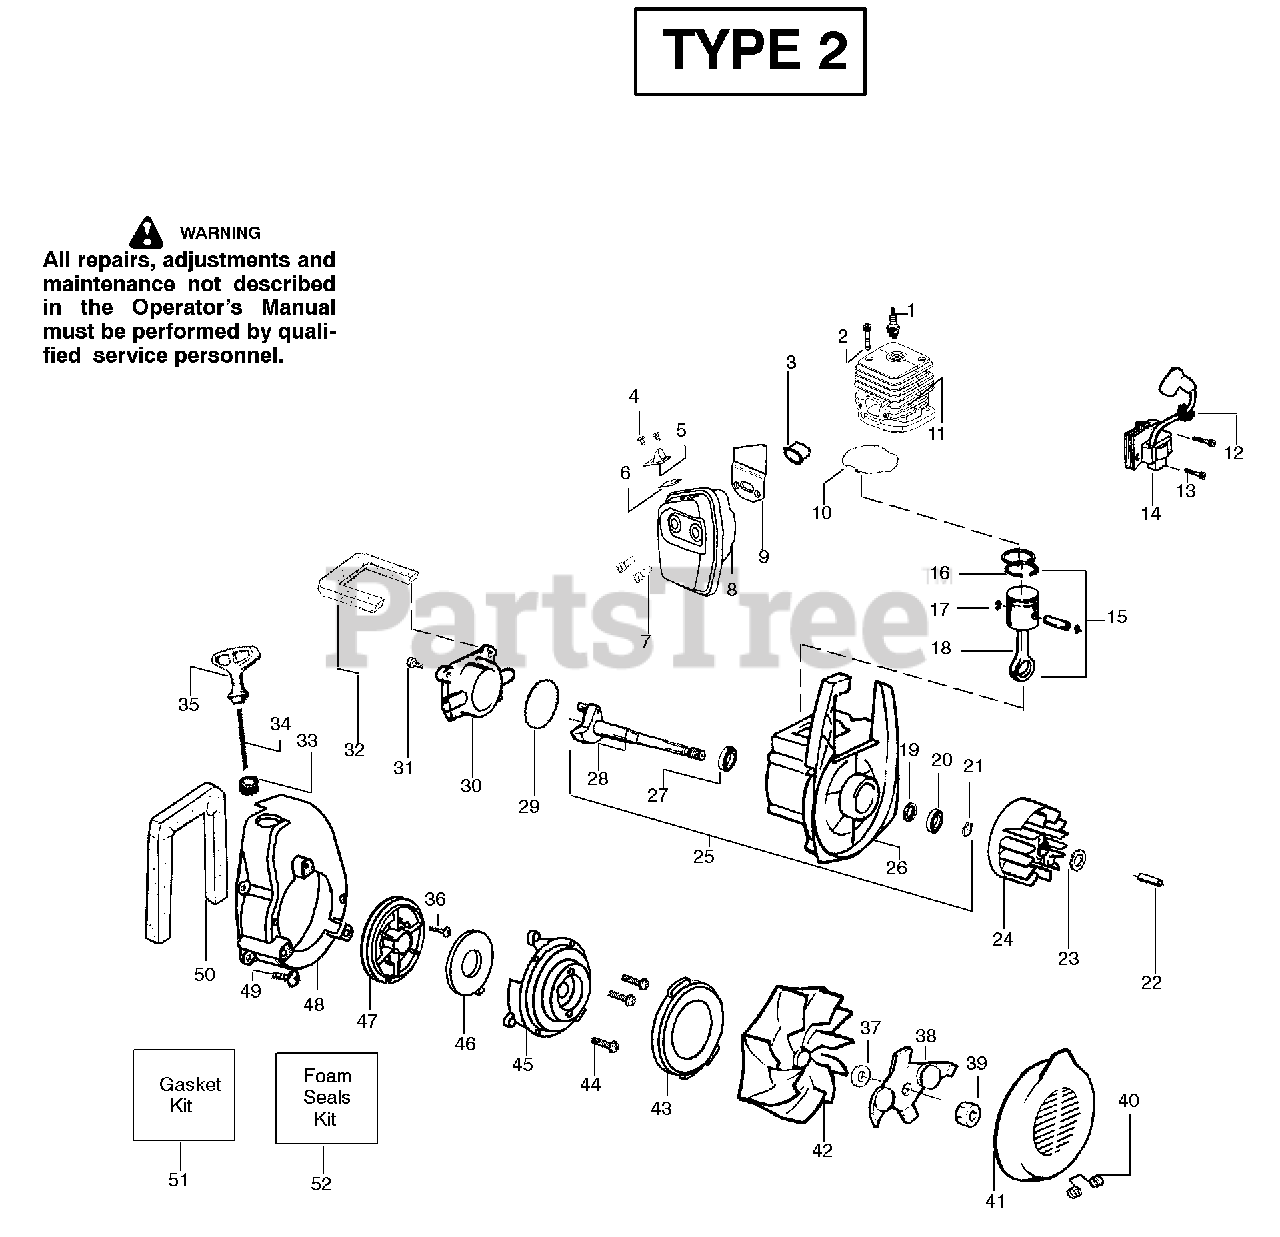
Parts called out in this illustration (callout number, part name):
1	Spark Plug (RCJ-6Y)
3	Insulator-Heat
5	Deflector-Muffler
6	Kit-Spark Screen
7	Screw-Muffler-Internal
8	Kit-Muffler
9	Gasket-Baffle (kit)
10	Gasket-Cylinder (kit)
11	Kit-Cylinder
12	Grommet-Ign. Module
13	Screw-Ignition Module
14	Module-Ignition
15	Kit-Piston
16	Ring-Piston
17	Retainer-Piston Pin
18	Assy-Connecting Rod
19	Seal-Crankcase
20	Bearing-Outer
21	Retainer Ring-C'chaft
22	Spacer-Flywheel
24	Assy-Flywheel
25	Assy-Crankcase/Crankshaft
26	Assy-Crankcase
27	Bearing-Inner
28	Assy-Crankshaft
29	O-ring-C/case (kit)
30	Cover-Crankcase
31	Screw
32	Foam-219mm (kit)
33	Eyelet-Flange
34	Kit-Rope
35	Handle-Starter
36	Screw-Rope
37	Washer-Belleville
38	Assy-Mulch Blade
40	Spring-Return Cover
41	Door-Inlet
42	Kit-Impeller Assy
43	Seal-Ring
45	Housing-Pulley
46	Spring-Starter
47	Kit-Starter Pulley
48	Housing-Fan
49	Screw
50	Foam-365mm (kit)
51	Kit-Gasket
52	Kit-Foam Seals
